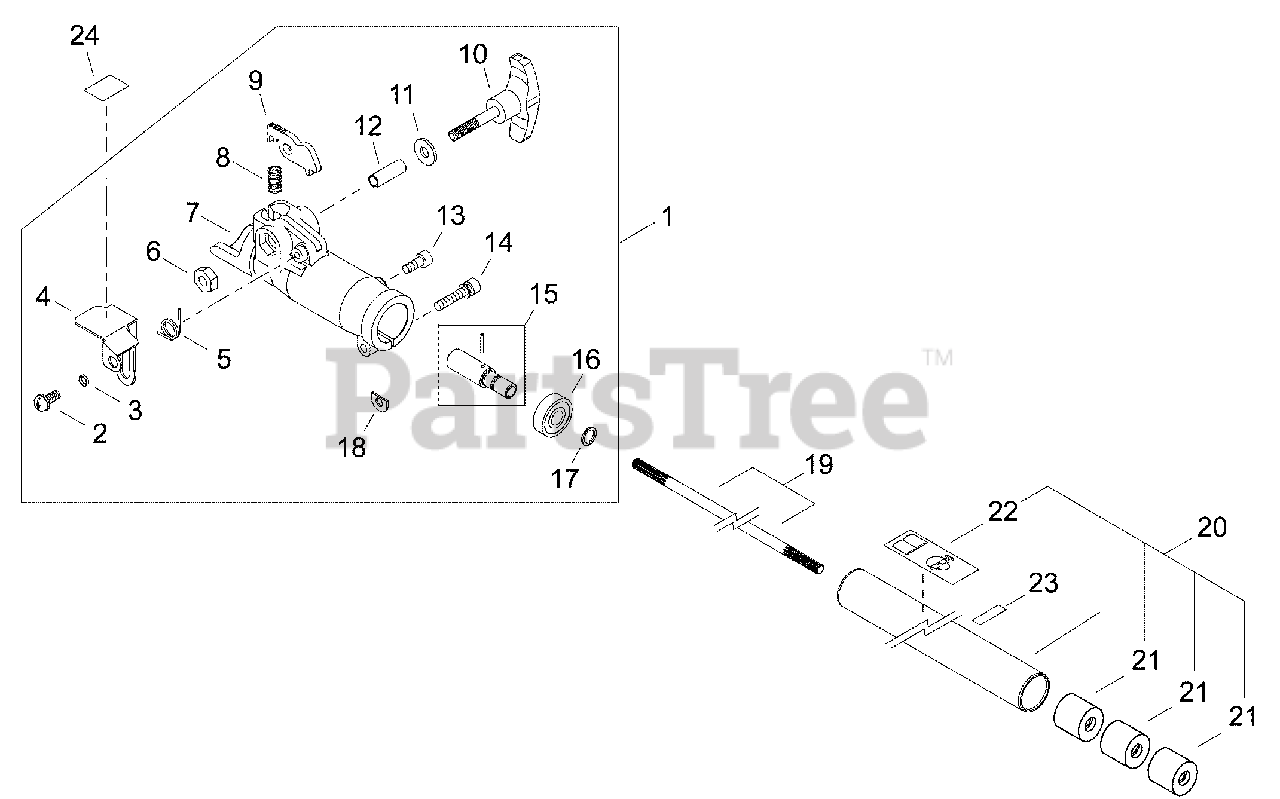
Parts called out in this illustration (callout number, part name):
1	COUPLER ASSY
2	SCREW M5×12
3	WASHER 5
4	PROTECTOR, LATCH
5	SPRING, TORSION
6	NUT 6
7	HOUSING, COUPLER
8	SPRING
9	LATCH
10	KNOB, COUPLER SCREW
11	WASHER 6
12	COLLAR
13	BOLT 5×12
14	BOLT M5×25
15	SHAFT, COUPLER
16	BEARING, BALL 609ZZ
17	RING, SNAP
18	D-WASHER
19	MAINSHAFT
21	BUSHING
22	LABEL, CAUTION
23	LABEL, HANDLE
24	LABEL, LATCH INSTRUCTION
